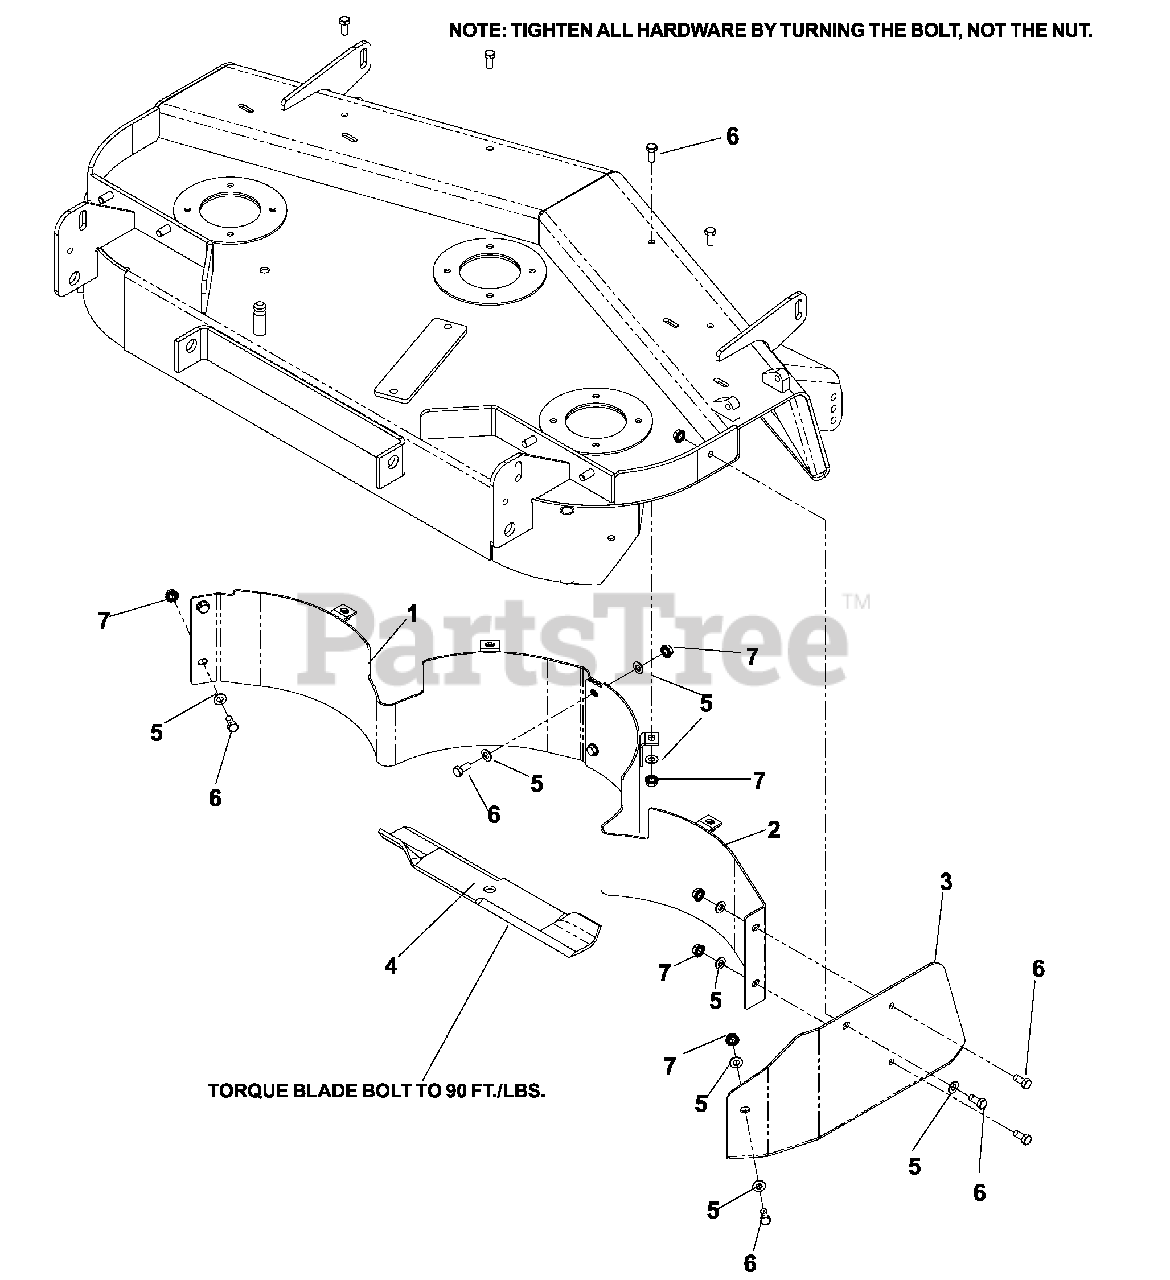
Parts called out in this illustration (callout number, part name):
1	42" BAFFLE, LEFT
2	42" BAFFLE, RIGHT
3	42" MULCH CAP
4	BLADE, MULCH, 14 5/8"
5	WASHER, 5/16, SAE
6	HCS, 5/16-18 X 3/4, GR5
7	NUT, 5/16C
